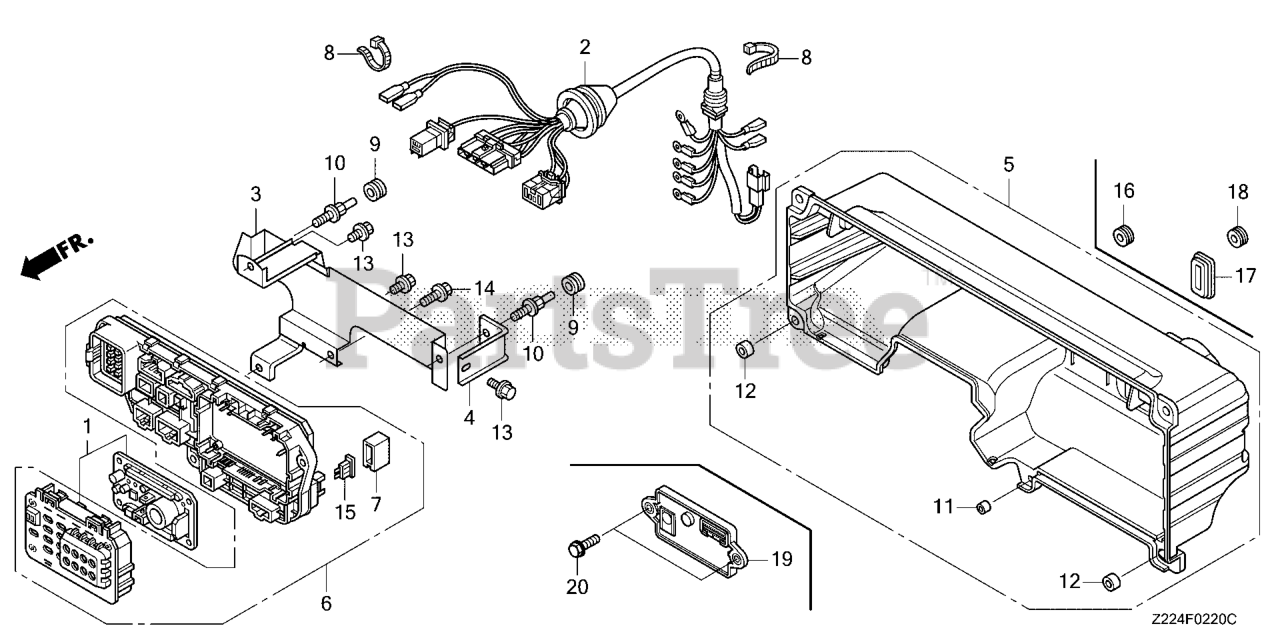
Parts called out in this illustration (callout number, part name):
1	COVER ASSY., AUTOMATIC VOLTAGE REGULATOR
2	WIRE HARNESS ASSY., GENERATOR (EB-A)
3	BRACKET, JUNCTION BOX
4	PLATE, JUNCTION BOX
5	CASE, CONTROL PANEL
6	BOX ASSY., JUNCTION
7	COVER, FUSE
8	TIE, CABLE (C)
9	GROMMET, SEAT LOCK LEVER
10	BOLT, FLANGE (6X18)
11	COLLAR, CONTROL CASE
12	COLLAR, CONTROL CASE
13	BOLT, FLANGE (6X10)
14	BOLT, FLANGE (6X14)
15	FUSE, BLADE (20A)
